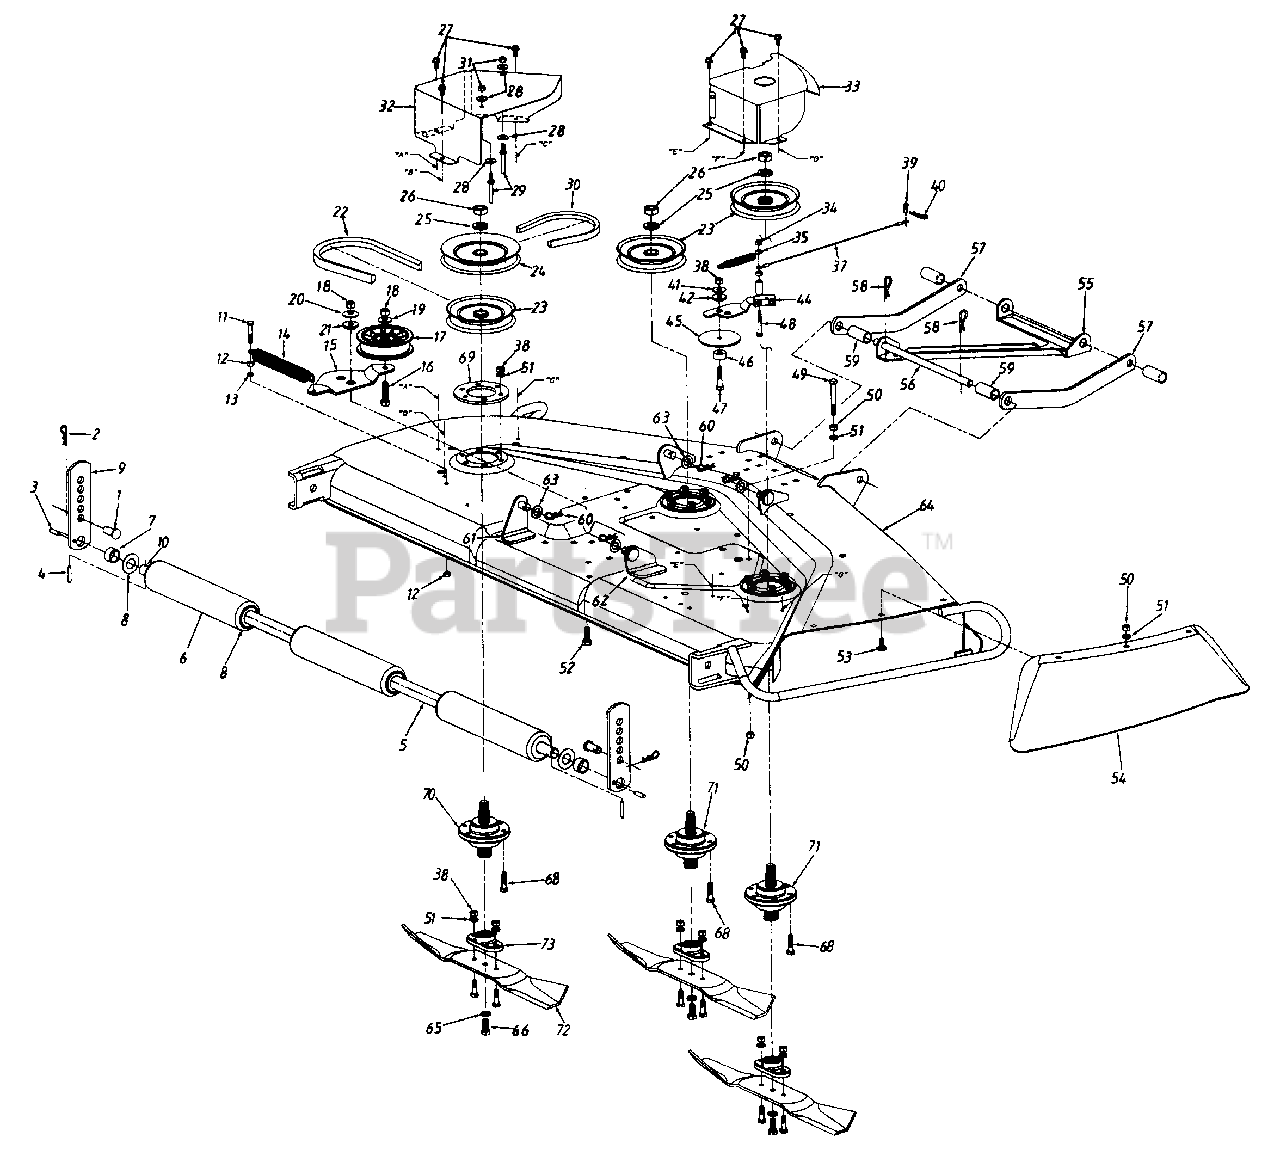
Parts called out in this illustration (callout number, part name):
1	Clevis Pin
2	Hairpin Clip
3	Spring Pin 1/4" x 1" Lg.
4	Spring Pin 3/16" x 1-1/4" Lg.
7	Spacer .75" I.D.
8	Fl-Wash. .76" I.D. x 1.5" O.D.
10	Roller Shaft
11	Hex Bolt 1/4-28 x 1.5" Lg. (Gr. 5)
12	Hex Nut 1/4-28 Thd.
13	L-Wash. 1/4" I.D.
14	Ext. Spring 7.33" Lg.
17	Idler Pulley
18	Hex Nut 3/8-24 Thd.
19	Bell-Wash. 3/8" I.D.
20	Bell-Wash. .39" I.D. x 1.13" O.D.
21	Shld. Spacer .625" I.D.
22	"V"-Belt
23	Deck Pulley
24	Upper Deck Pulley
25	L-Wash. 5/8" I.D.
26	Hex Jam Nut 5/8-18 Thd.
27	Hex Wash. Hd. Scr. 1/4-20 x .5" Lg.
28	Bell-Wash. 1/4" I.D.
29	Belt Guard Pin
30	"V"-Belt
31	Hex Nut 1/4-20 Thd.
35	Ext. Spring 3.97" Lg.
37	Brake Cable
38	Hex Nut 5/16-24 Thd.
39	Clevis Pin
40	Hairpin Clip
41	Bell-Wash. .325" I.D.
42	Shld. Spacer
44	Brake Ass'y.
45	Fl-Wash. 5/16" I.D. x .3" O.D.
46	Spacer .44" Lg.
47	Hex Bolt 5/16-24 x 1.5" Lg. (Gr. 5)
48	Hex Bolt 1/4-28 x 1.75" Lg. (Gr. 5)
49	Hex Bolt 5/16-18 x 2.5" Lg.
50	Hex Nut 5/16-18 Thd.
51	L-Wash. 5/16" I.D.
52	Hex Bolt 3/8-24 x 1" Lg.
53	Carr. Bolt 5/16-18 x .75: Lg.
59	Spacer 1.75" Lg.
60	Hairpin Clip
63	FL-Wash. 1/2" I.D. x .93" O.D.
66	Hex Bolt 3/8-24 x .88" Lg. (Gr. 5)
68	Hex Bolt 5/16-24 x 1-1/4" Lg. (Gr. 5)
69	Spindle Reinforcement Plate
70	Spindle Ass'y. (L.H.)
71	Spindle Ass'y. (R.H. & Center)
72	Blade
73	Blade Adapter
